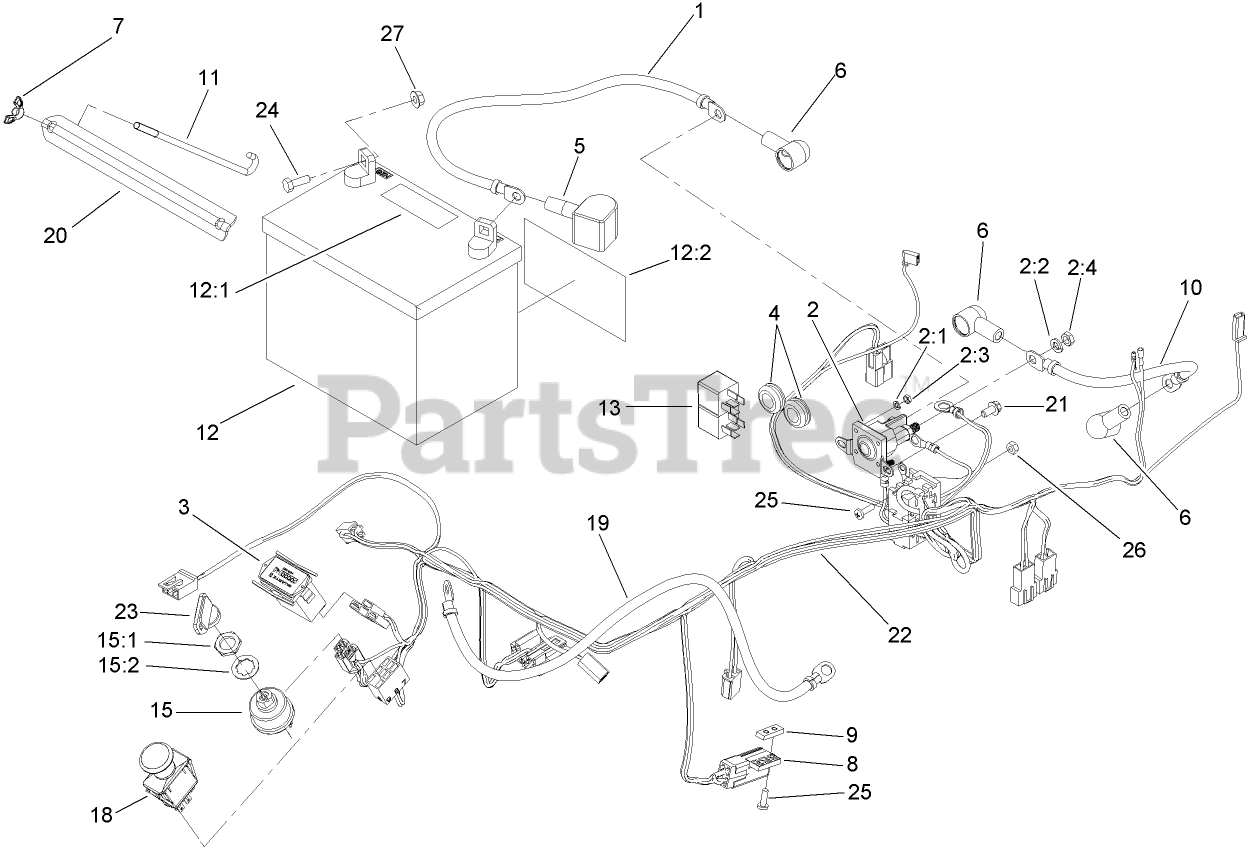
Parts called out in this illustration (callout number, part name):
1	CABLE-BATTERY, POSITIVE
2	SWITCH-SOLENOID
2:1	WASHER-LOCK
2:2	WASHER-LOCK
2:3	NUT-HEX
2:4	NUT-JAM
3	METER-HOUR
4	GROMMET
5	INSULATOR-BATTERY
6	INSULATOR-SOLENOID
7	WINGNUT
8	SWITCH
9	PLATE-TAPPED
10	CABLE-STARTER, POSITIVE
11	BOLT-HOLDDOWN
12	BATTERY
12:1	Decal-Battery
12:2	Decal-Battery
15	SWITCH ASM
15:1	NUT-HH
15:2	WASHER-TOOTH, INTERNAL
18	SWITCH-PTO
19	CABLE-BATTERY, NEGATIVE
20	ANGLE-BATTERY
21	SCREW-HWH
22	HARNESS-WIRE
23	KEY-IGNITION
24	SCREW-HH
25	SCREW-PPH
26	NUT-LOCK, NI
27	NUT-HF
